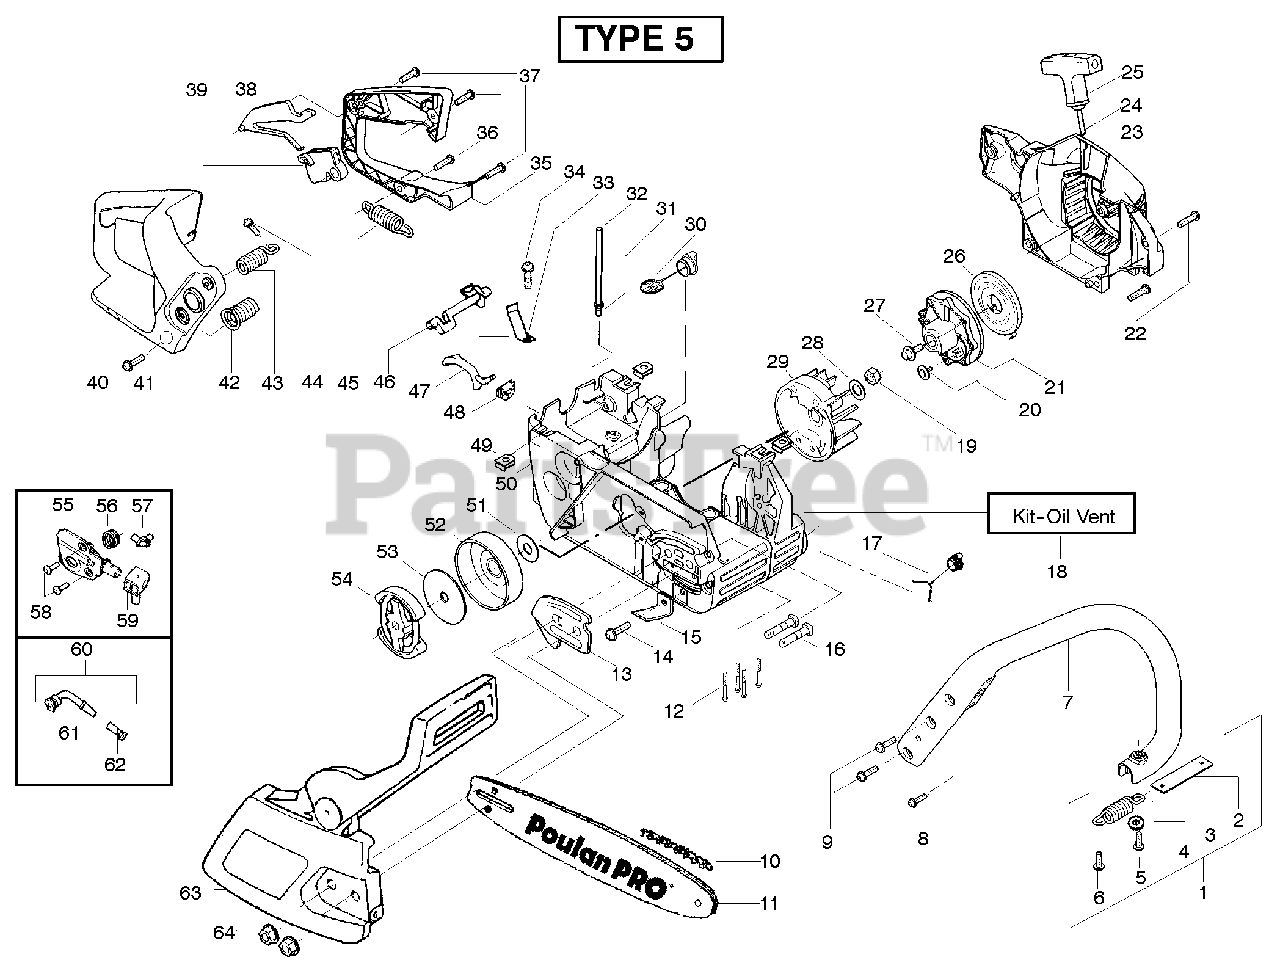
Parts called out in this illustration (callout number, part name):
1	Assy.-Isolator
2	Limiter Strap
3	Spring-Isolator
4	Washer
7	Front Handle
10	Chain - 16"
11	Bar- 16"
13	Plate-Bar Mount.
15	Chain Catcher
16	Bolt-Bar
17	Assy-Oil Cap
18	Kit-Oil Vent
19	Nut-Flywheel
21	Starter Pulley
23	Housing-Fan
24	Kit - Rope
25	Handle-Starter
26	Spring-Recoil
28	Washer-Flywheel
29	Assy-Flywheel
30	Assy-Fuel Cap
31	Fitting-fuel line
32	Kit-Fuel line (large)
33	Spring-Switch
35	Cover-Rear Handle
38	Throttle Lockout
39	Trigger-Throttle
40	Handle - Rear
41	Screw
42	Assy Isolator-lower
43	Kit-Isolator (Upper)
45	Spring-Isolator
46	Lever-Switch
47	Lever-Choke
48	Grommet-Knob
49	Nut-"U"-Type
50	Assy-Chassis
51	Washer-Thrust
52	Assy.-Clutch Drum w/bearing
53	Washer-Clutch
54	Assy. Clutch
55	Kit - Oil Pump
56	Gear-Worm Spring
57	Elbow-Oil Pickup
59	Seal Block
60	Assy-Oil Pick-up
61	Pick-up Oiler
62	Filter-Oil
63	Assy.-Chain Brake
64	Nut-Bar Mounting
